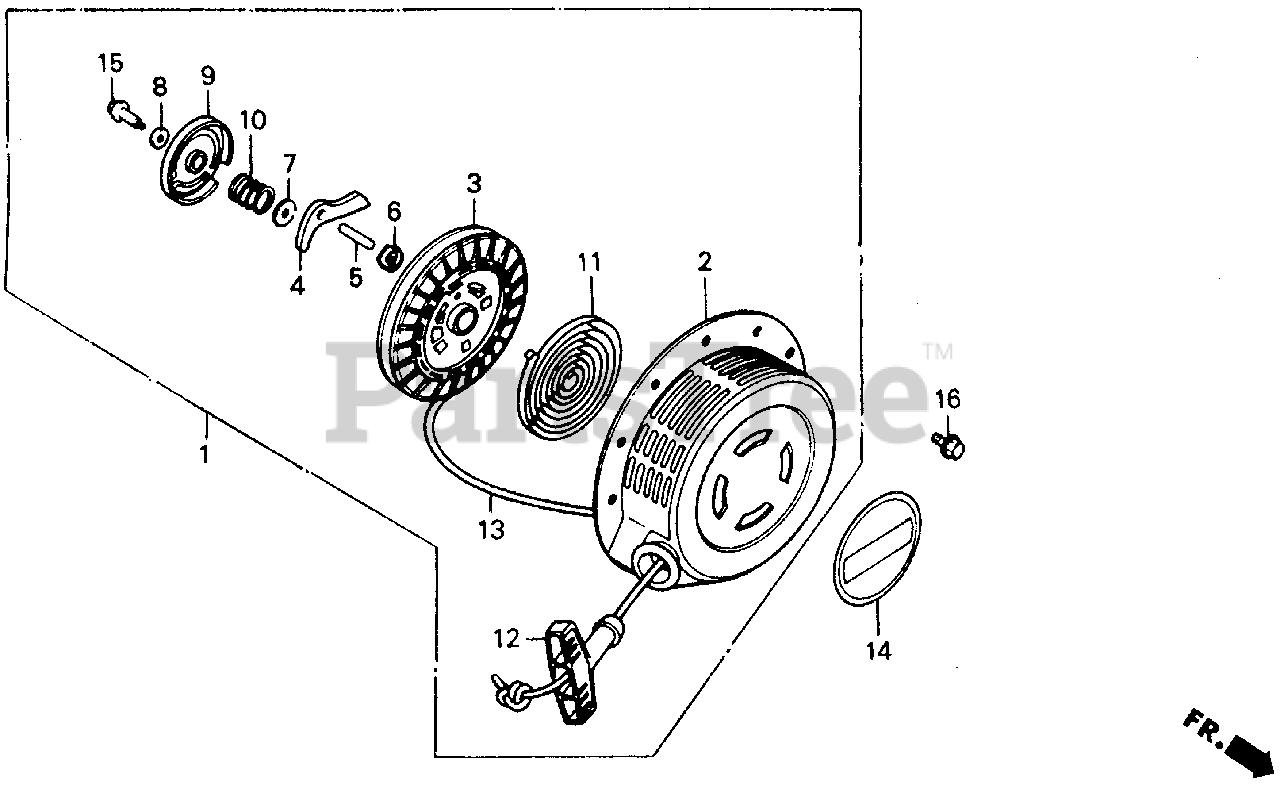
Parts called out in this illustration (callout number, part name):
1	STARTER ASSY., RECOIL *R8* (BRIGHT RED)
2	CASE, RECOIL STARTER *R8* (BRIGHT RED)
3	REEL, STARTER
4	RATCHET, STARTER
5	SHAFT, RATCHET
6	PLATE, GUIDE
7	PLATE A, FRICTION
8	PLATE B, FRICTION
9	COVER, REEL STARTER
10	SPRING, FRICTION
11	SPRING, RETURN
12	GRIP, STARTER
13	ROPE, STARTER (#6X64") (N/A: USE ALT P/N 08560-ZG921-11)
14	EMBLEM (EXP-ALERT)
15	BOLT, REEL COVER
16	BOLT, FLANGE (6X8)
